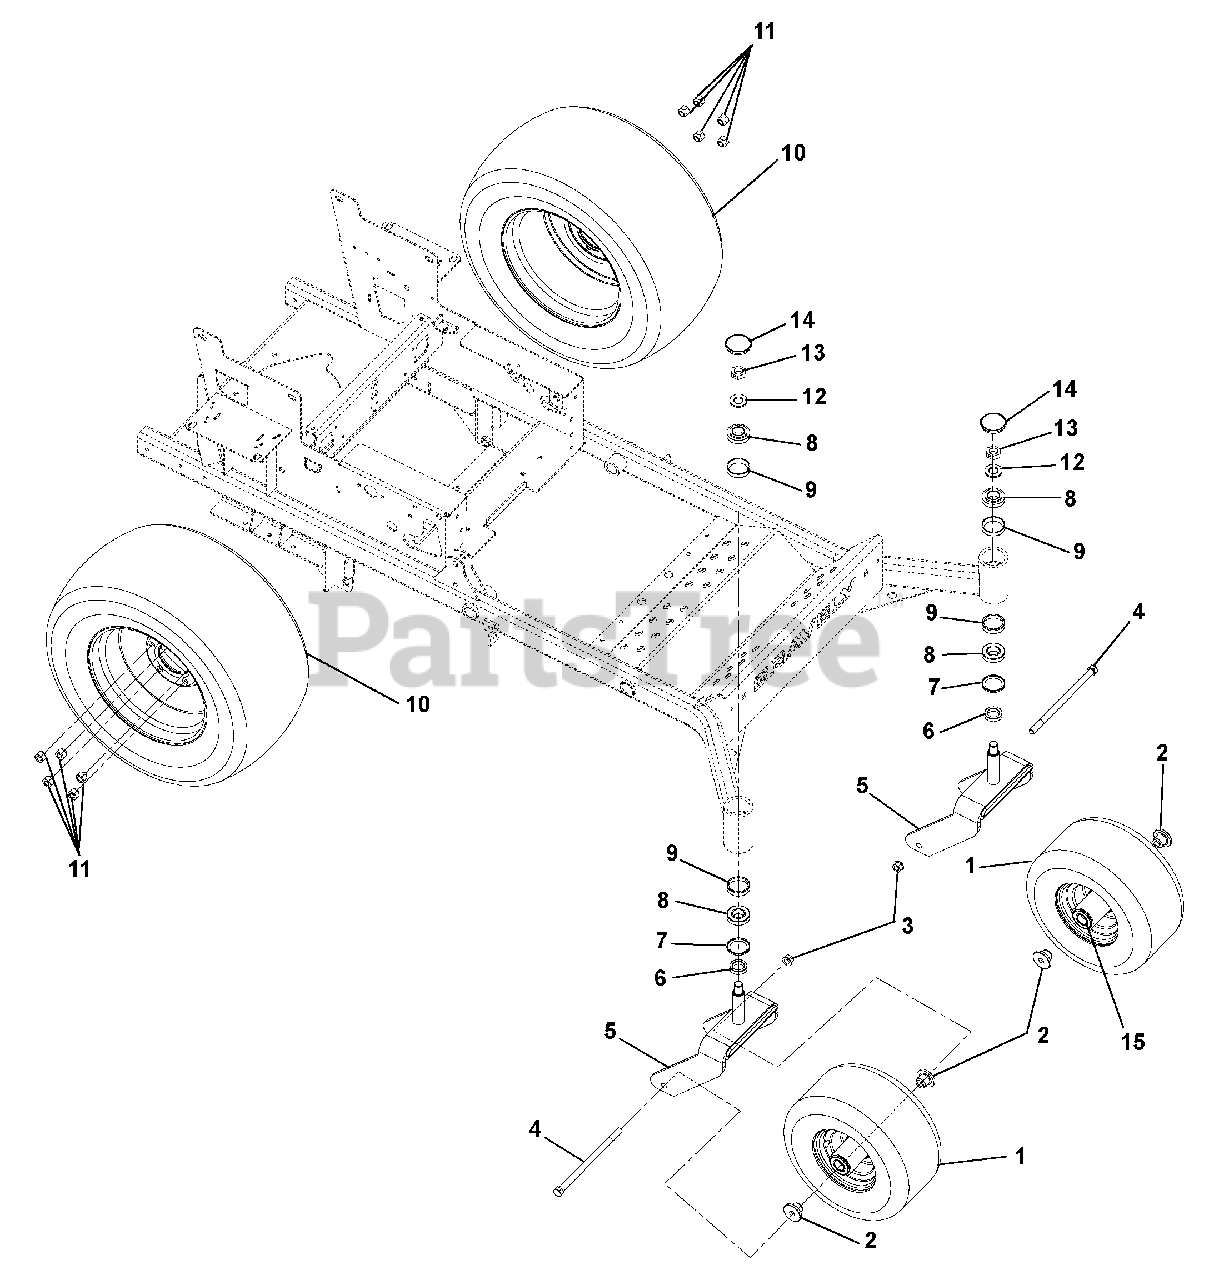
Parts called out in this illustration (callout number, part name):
1	Tire/Wheel Assembly, 13 x 6.50-6
2	Spacer, Front Wheel
3	Nut, .50-13 Nyloc Flange
4	Bolt, Hex .50-13 X 9.00 Grade 5
5	Fork
6	Spacer 1.005 x 1.5075 x .375
7	Bearing Seal 1.5 x 2 x .18 Transcom
8	Bearing, Cone 1.0 x .58 Pre-Greased
9	Bearing, Cup 1.980 x .420
10	Tire/Wheel Assembly, 23 x 10.00-12
11	Nut, Wheel .50-20 13/16 Across Flats Automotive Type
12	Washer, Flat Steel .812 x 1.50 x .135
13	Nut, Jam Center-Lock .75-16
14	Cap, Dust
15	Bearing, 25MM ID x 52MM OD x 15MM
